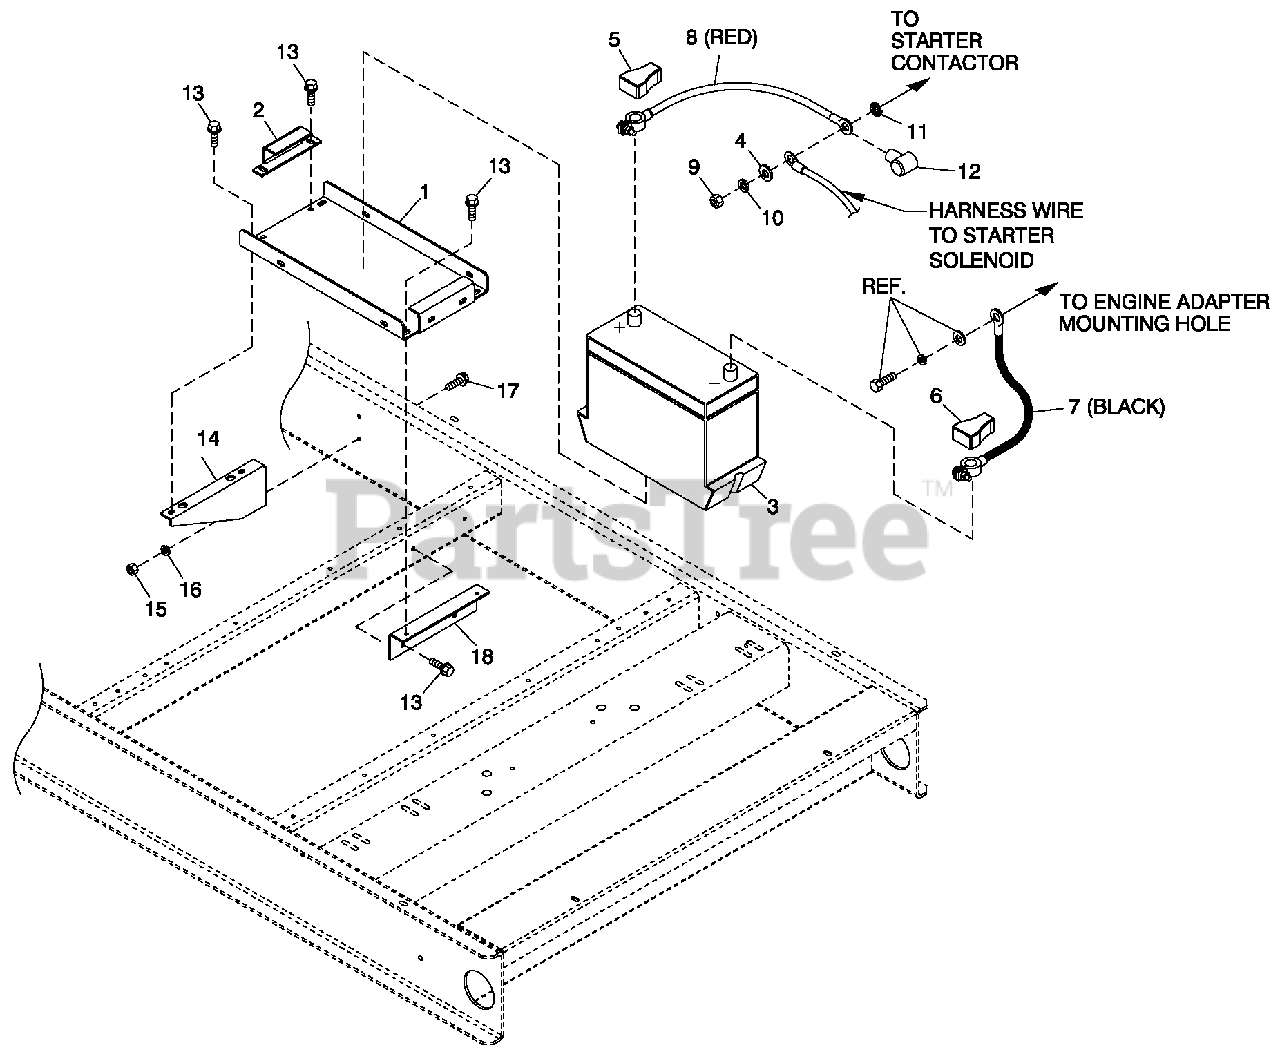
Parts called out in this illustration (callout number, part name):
1	TRAY BATTER 27F
2	STRAP BATTERY RETAINMENT 27F
3	BATTERY 12VDC 90-AH 27F
4	WASHER FLAT 3/8-M10 ZINC
5	BATTERY POST COVER RED +
6	BATTERY POST COVER BLK -
7	CABLE BATTERY BACLK #1 X 26.00
8	CABLE BATTERY RED #1 X 28.00
9	NUT HEX M8-1.25 G8 YEL CHR
10	WASHER LOCK M8-5/16
11	WASHER SHAKEPROOF EXT 5/16 STL
12	BOOT BATTERY CABLE
13	SCREW THF M6-1 X 16 N WA Z/JS
14	SUPPORT BATTERY TRAY
15	WASHER LOCK M6-1/4
16	NUT HEX M6 X 1.0 G8 YEL CHR
17	SCREW HHC M6-1.0 X 20 G8.8
18	SUPPORT 27F BATTERY
